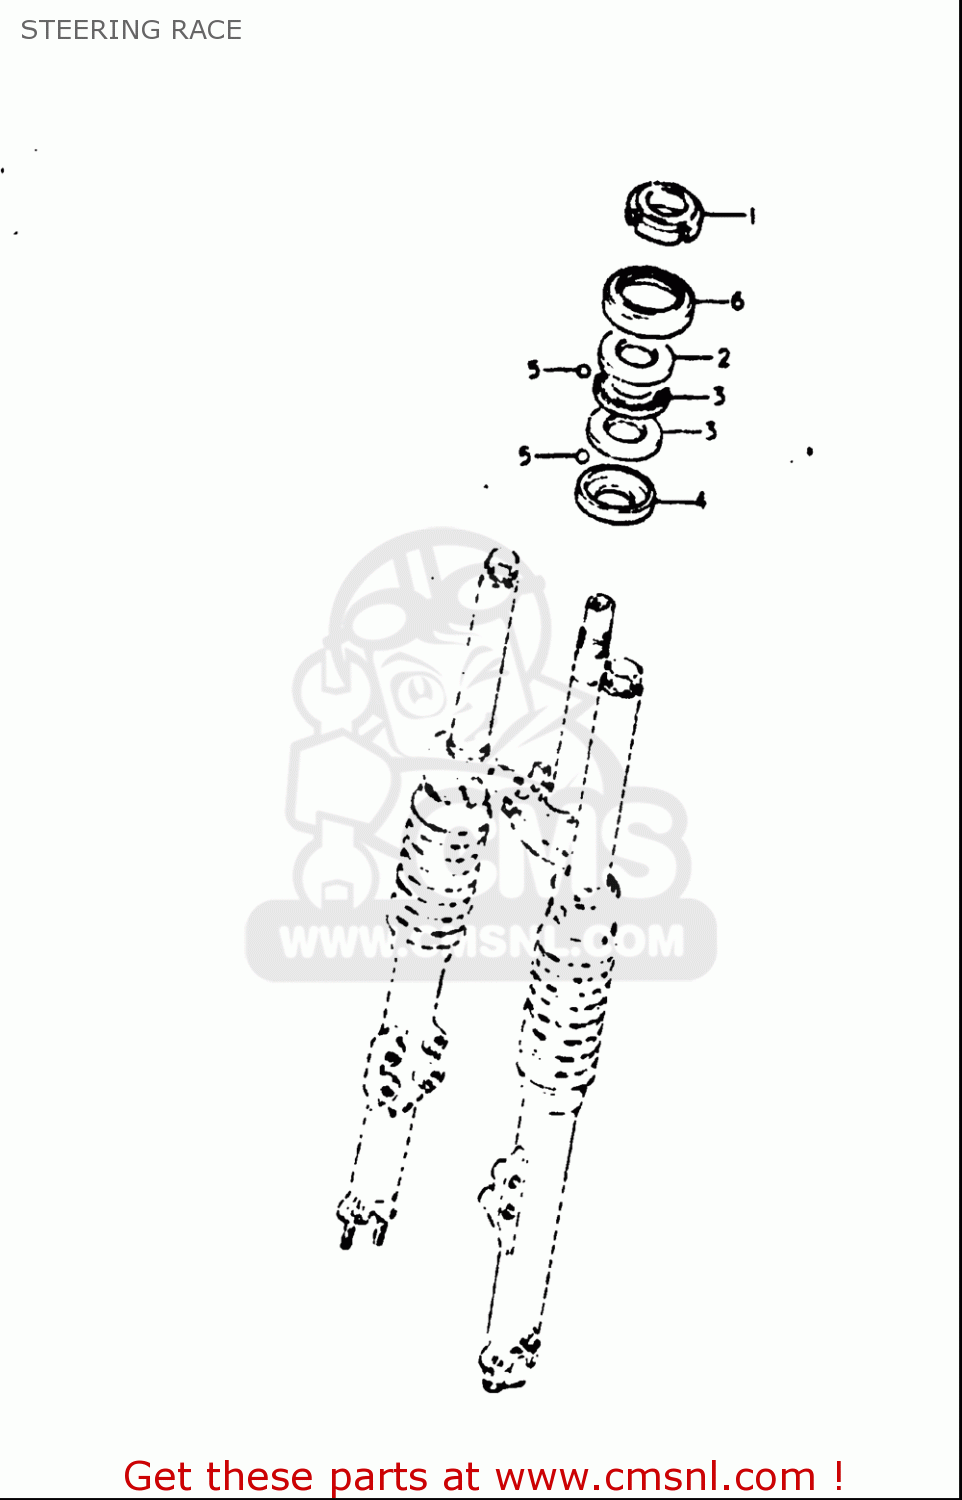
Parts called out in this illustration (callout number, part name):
1	NUT,STEERING STEM(25X44X10)
2	LACE,STEERING OUTER UPR
3	LACE,STEERING INNER LWR
4	RACE,STEERING OUTER LWR
5	BALL
6	DUST SEAL,STEERING UPR
